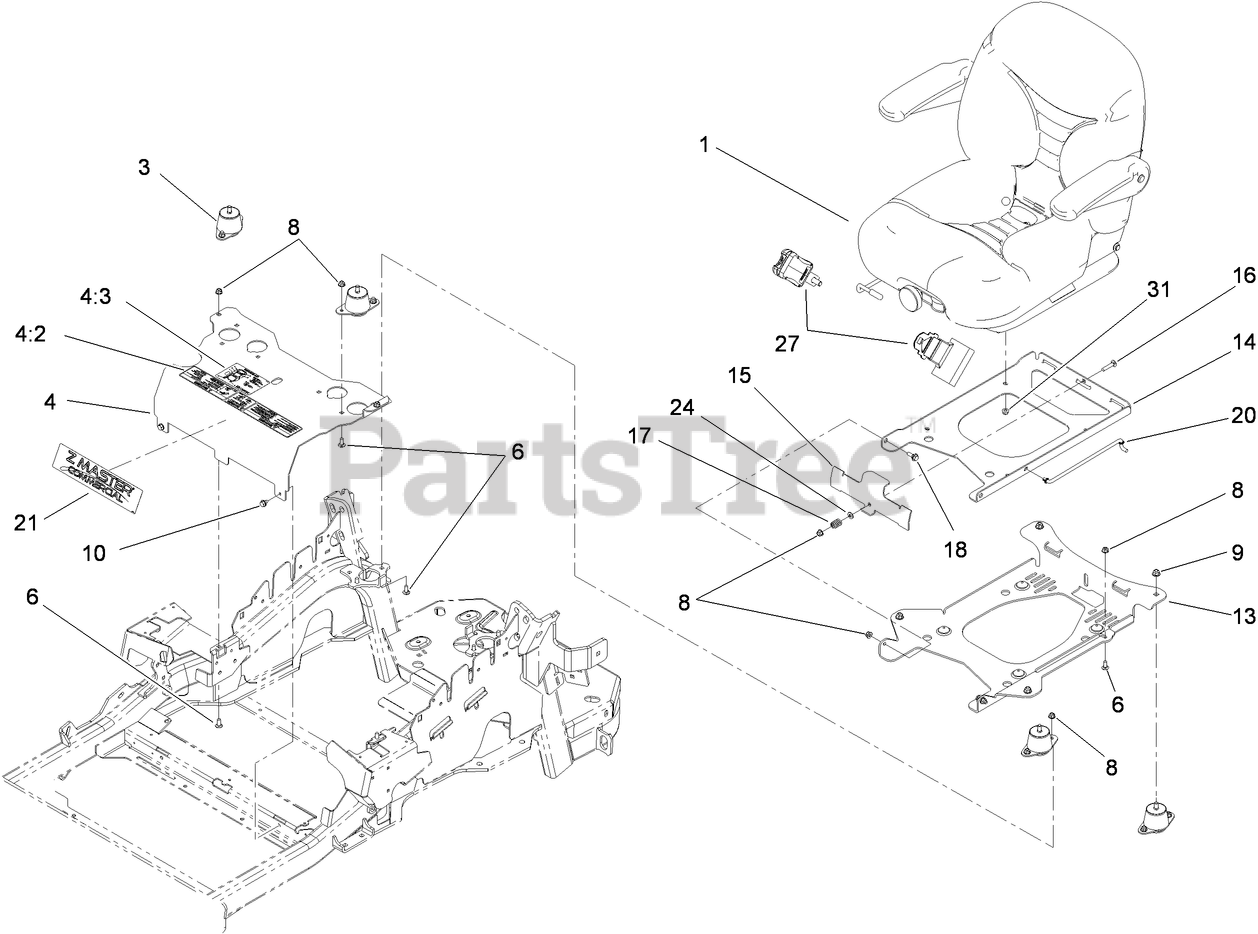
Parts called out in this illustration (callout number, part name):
1	SEAT ASM
3	ISOLATOR-SEAT
4	MOUNT-SEAT
4:2	DECAL-CONSOLE
4:3	DECAL-SERVICE AID
6	SCREW-CARR
8	NUT-HF, NI
9	NUT-HF, NI
10	SCREW
13	PLATE-SUPPORT, SEAT TILT
14	PLATE-FRAME, SEAT TILT
15	PLATE-LATCH, SEAT
16	BOLT-CARR
17	SPRING-COMPRESSION
18	SCREW-SHOULDER
20	ROD-PROP
24	WASHER-PLAIN
27	SEAT BELT KIT (SHORT)
31	NUT-HF
